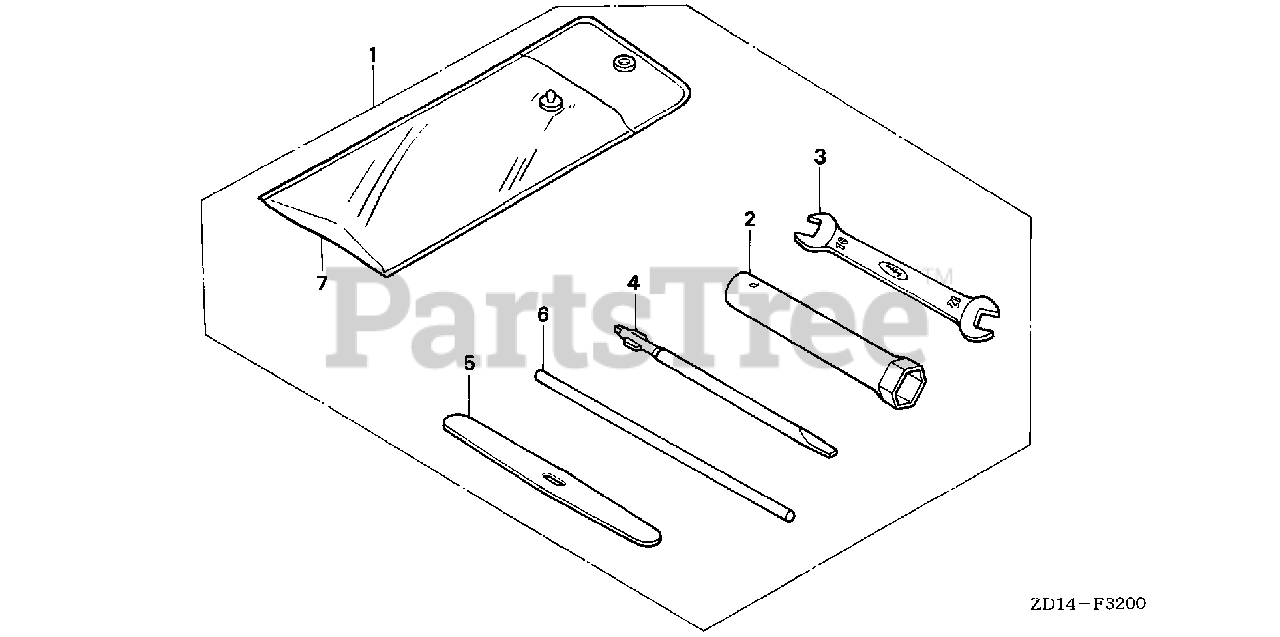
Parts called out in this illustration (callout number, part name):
1	TOOL KIT
2	WRENCH, PLUG
3	SPANNER (10X12)
4	DRIVER 3, MINUS SCREW (NO.2)
5	LEVER
6	BAR A, HANDLE
7	BAG, TOOL
